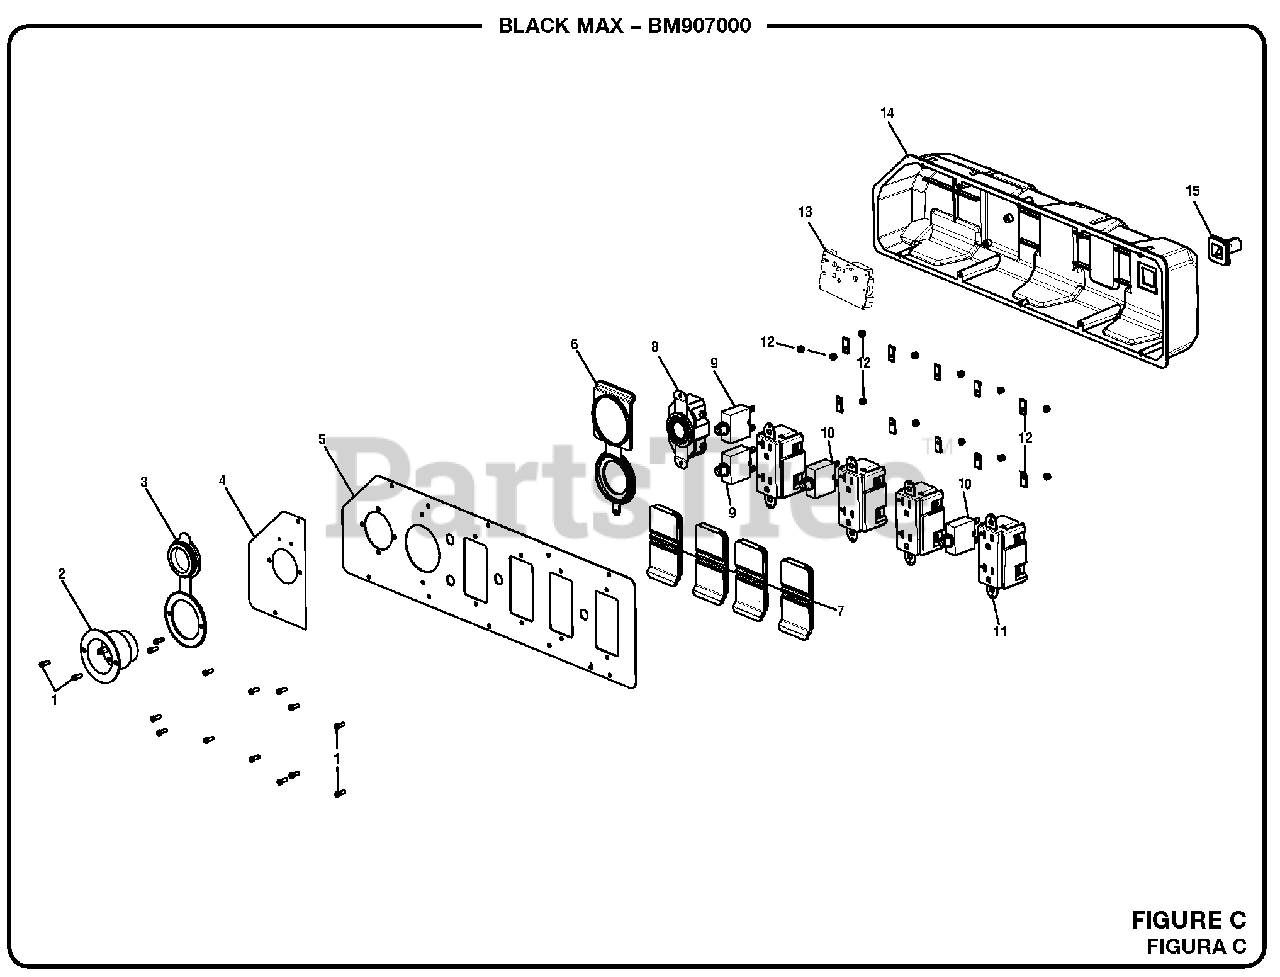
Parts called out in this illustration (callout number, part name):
1	Screw (6-20 x 3/8 in, Pan Hd)
2	120V Receptacle (15A)
3	120V Receptacle Cover
4	Control Panel Label
5	Control Panel Faceplate
6	Twist Lock Receptacle Cover
7	120V Duplex Receptacle Cover
8	120/240V Receptacle (30A)
9	Circuit Breaker (30A)
10	Circuit Breaker (20A)
11	120V Duplex Receptacle
12	Lock Nut (6-32, Hex Hd)
13	Circuit Board Assembly
15	Control Box
15	Wire Protector
